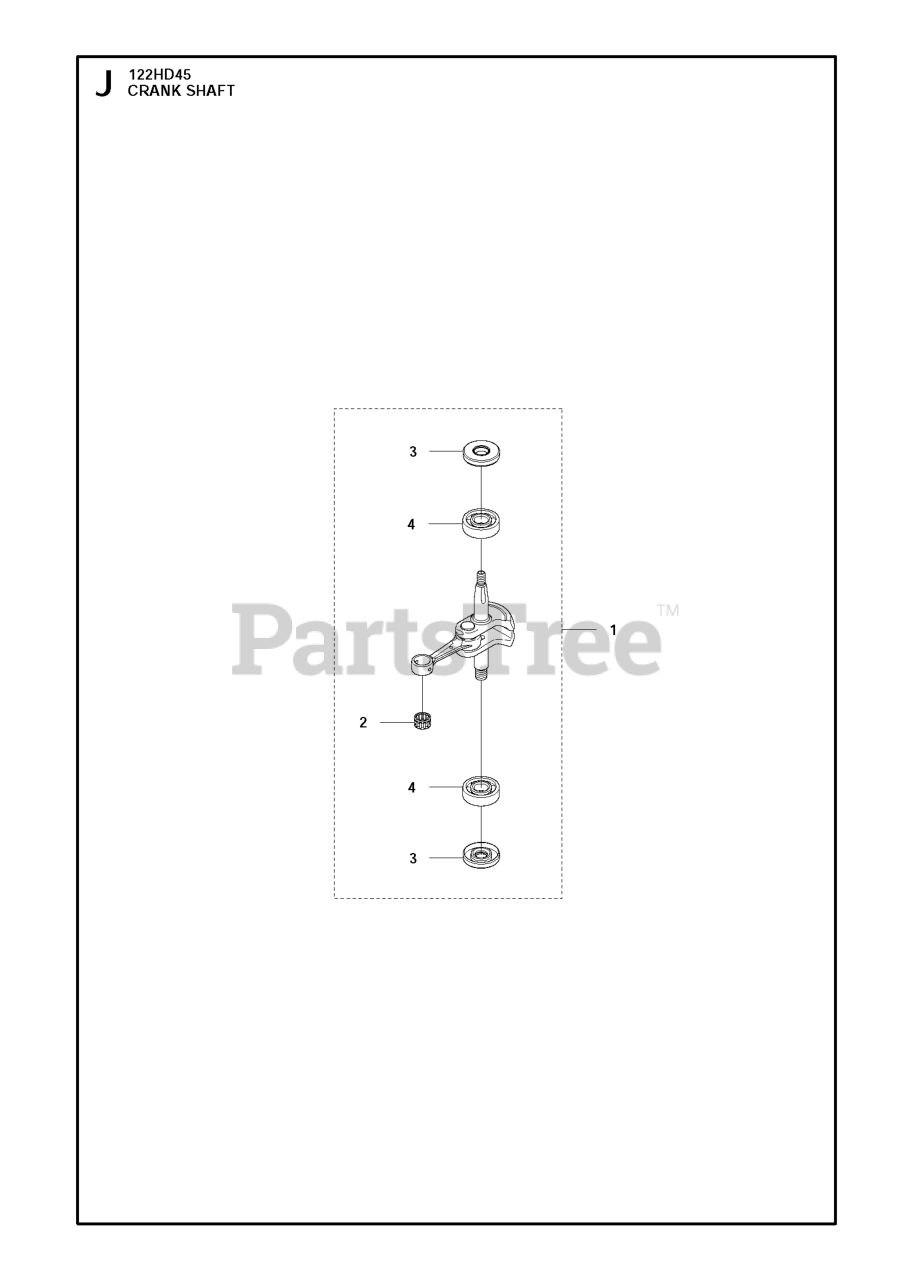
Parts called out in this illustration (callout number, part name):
1	CRANKSHAFT
2	NEEDLE BEARING
3	SEALING RING
4	BALL BEARING
9	WASHER BRB 8.4X17
44	PEDAL RUBBER, SF
45	PEDAL RUBBER
49	Cotter Pin
50	BALL BEARING 6002-2RS1
53	MICRO SWITCH
55	PEDAL SHAFT CLAMP
61	Clevis Pin
